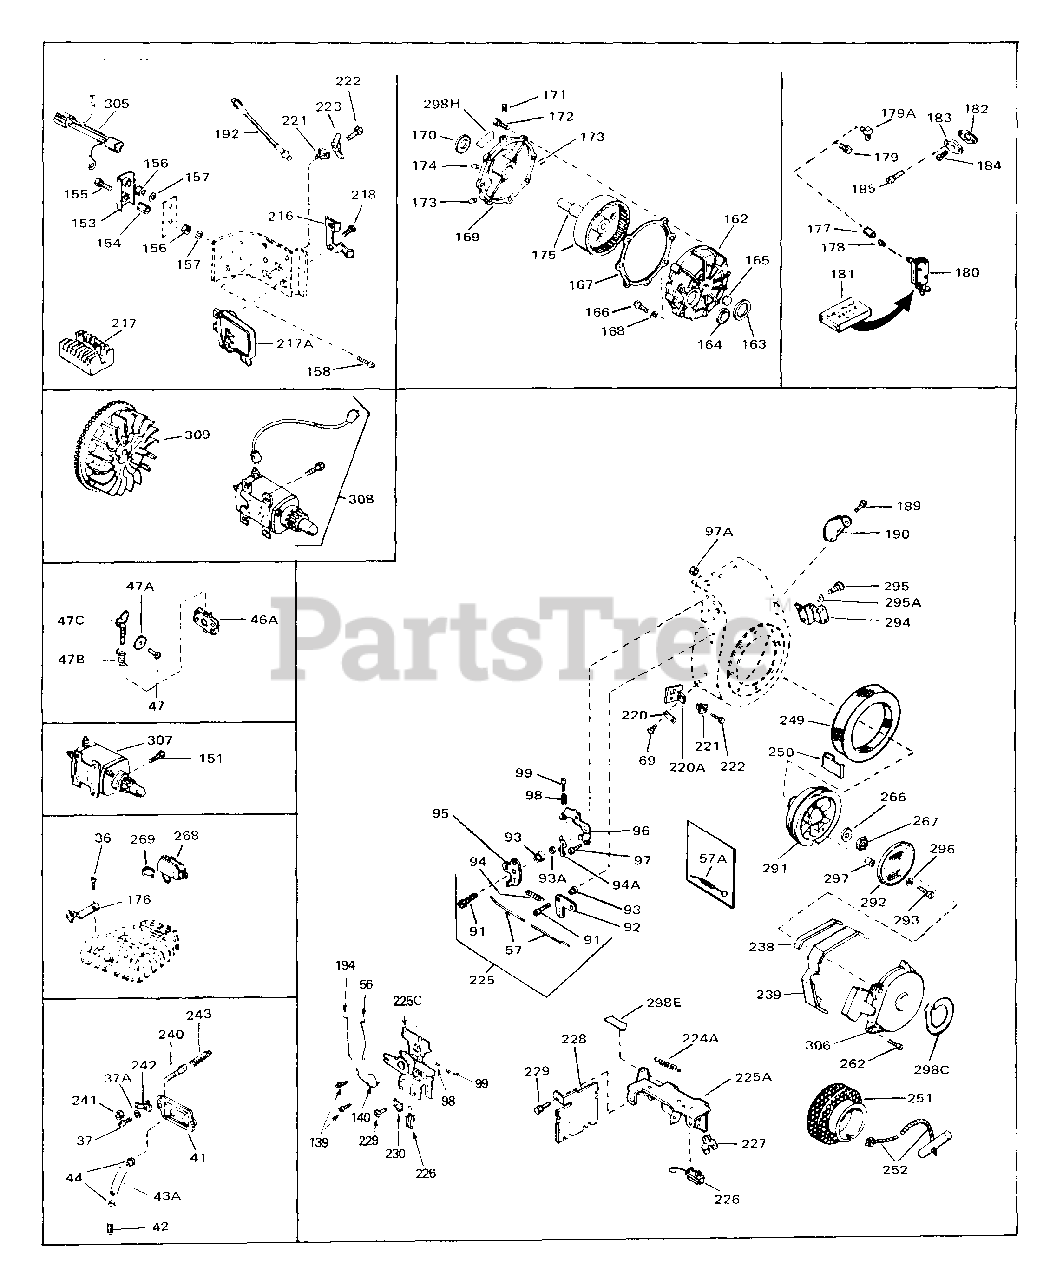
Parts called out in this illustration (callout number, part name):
36	Screw, Hex flange hd., 5/16-18 x 2
36	Screw, Hex flange hd., 5/16-18 x 2-1/ 4
36	Screw, Hex flange hd., 5/16-18 x 2-1/ 2
37	Screw, Fil. hd. Sems, 10-24 x 1/2
37	Screw, Hex washer hd., 10-24 x 5/8
37A	Washer, Flat
41	Cover, Valve spring
56	Link, Throttle
69	Screw
98	Spring, Compression
99	Screw, Fil hd., 5-40 x 7/16
99	Screw, Hex hd., 10-32 x 1 (Drilled th ru)
182	Gasket, Fuel pump cover
183	Cover, Fuel pump pad
184	Plug, Pipe 1/8-27
185	Screw Hex hd. Sems, 1/4-20 x 1/2
225	Control Assy., Speed
226	Terminal Assy.
227	Terminal
230	Clip, Conduit
246	Retainer, Bearing
266	Washer, Belleville
267	Nut, Hex
305	Harness Assy., Adapter
306	Starter, Rewind
308	Starter Motor Kit (110-120 Volt)
309	Flywheel
